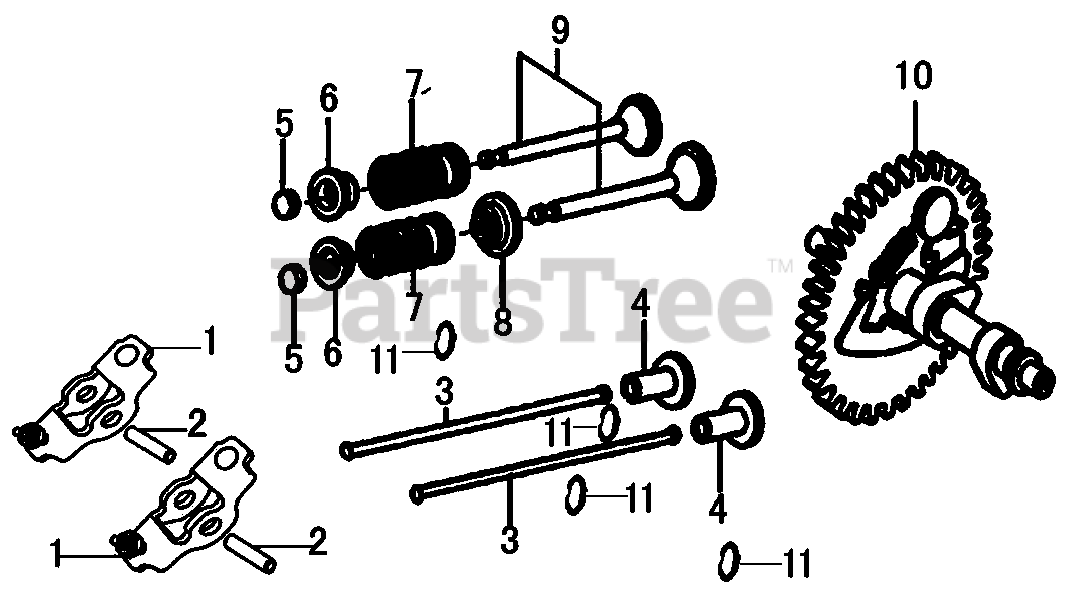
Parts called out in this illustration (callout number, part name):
1	ARM, ROCKER
2	VALVE ROCKER SHAFT
3	ROD, PUSH
4	VALVE, LIFTER-TAPPET
5	VALVE, ROTATOR
6	RETAINER, VALVE SPRING
7	SPRING, VALVE
8	SEAL, GUIDE
9	VALVE SET
10	CAMSHAFT ASSY.
11	WASHER, SPLIT
